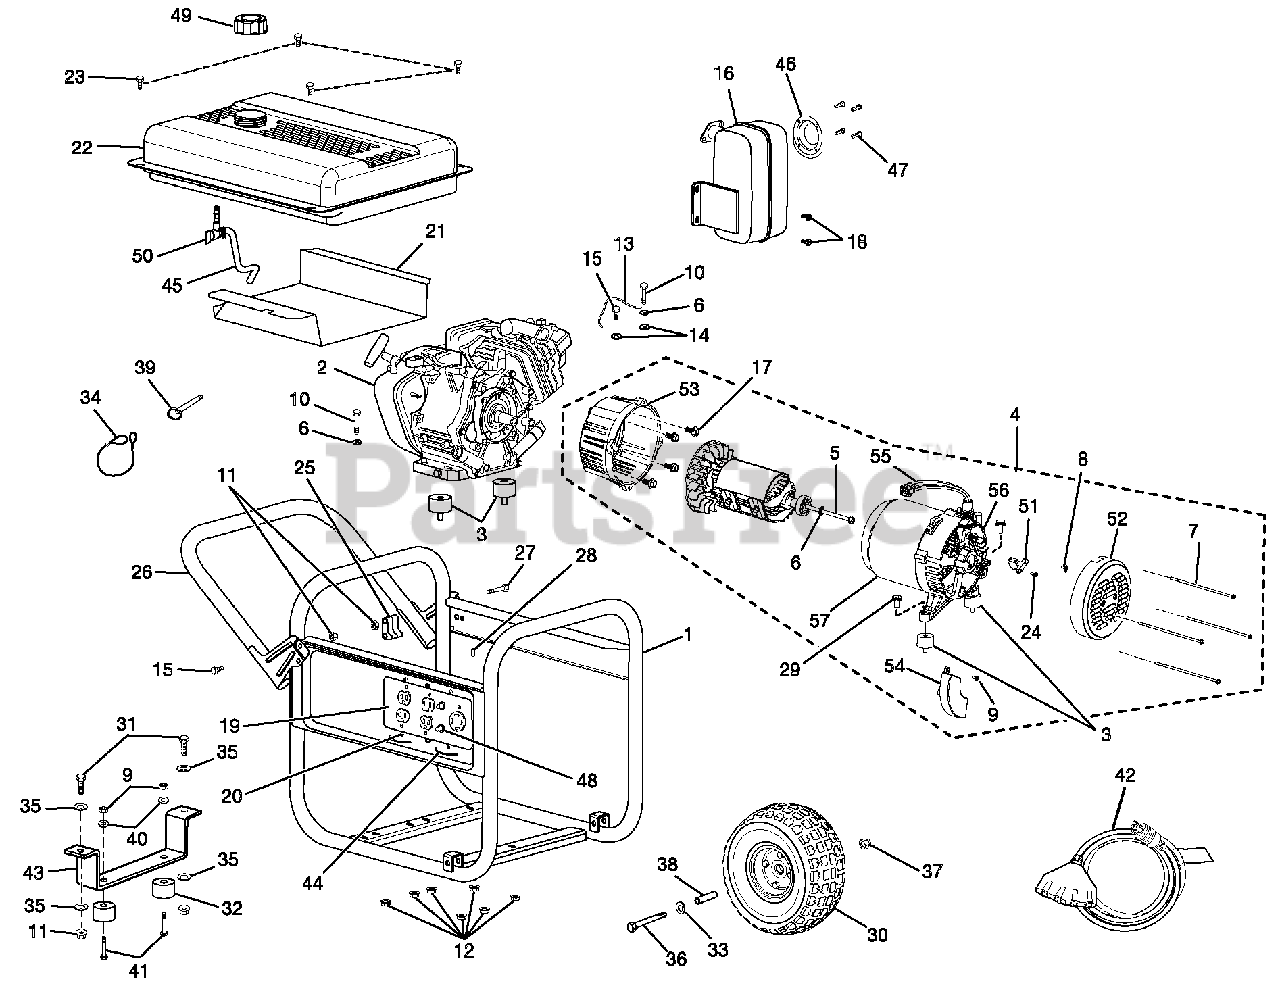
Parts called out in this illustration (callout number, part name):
1	Frame Assembly
2	Engine (Subaru OHC)
4	Generator Head Assembly
5	Bolt (5/16-24 x 8.5 in., Hex Hd.)
6	Lock Washer (5/16 in.)
7	Bolt (1/4-20 x 6 in., Hex Hd.)
8	Ground Lug
9	Bolt, AVR Mounting
10	Bolt (5/16-18 x 1-1/2 in.)
11	Lock Nut (5/16-18)
12	Flange Nut (5/16-18)
13	Ground Wire Assembly
14	Washer (5/16 in.) External Star
15	Bolt (5/16-18 x 3/4 in., Hex. Hd.)
17	Bolt (3/8-16 x 3/4 in.)
18	Bolt (5/16-24 x 5/8 in.)
19	Wire Panel
20	Screw (6-19 x 1/2 in.)
21	Heat Shield
22	Fuel Tank Assembly
23	Screw (#10 x 1 in.)
24	Bolt, Mounting Brush Assembly
25	Handle Lock Bracket
26	Handle Assembly
27	Bolt (5/16-18 x 2-1/4 in.)
28	Rubber Cap
29	Bolt (5/16-18 x 1-1/2 in., Hex Hd.)
31	Bolt (5/16-18 x 1 in.)
32	Rubber Foot
33	Washer (3/8 in.)
35	Washer (5/16 in.)
36	Bolt (3/8-16 x 4-1/4 in.)
37	Lock Nut (3/8-16)
38	Spacer (.38 ID)
39	Handle Lock Pin
40	Washer (1/4 in.)
41	Bolt (1/4-20 x 1-1/2 in.)
42	Extension Cord (25 foot, 20 amp)
43	Frame Support
44	Cord Retainer
45	Fuel Line Assembly
46	Spark Arrester Screen
47	Screw (8-32 x 3/8 in.)
48	Circuit Breaker (20 amp)
50	Fuel Shut Off Valve with Filter
51	Brush Assembly Kit
52	Brush Cover
53	Adapter Housing
54	Automatic Voltage Regulator (5000 Watt)
55	Wiring Harness
56	Bearing Support
57	Generator Head Cover
